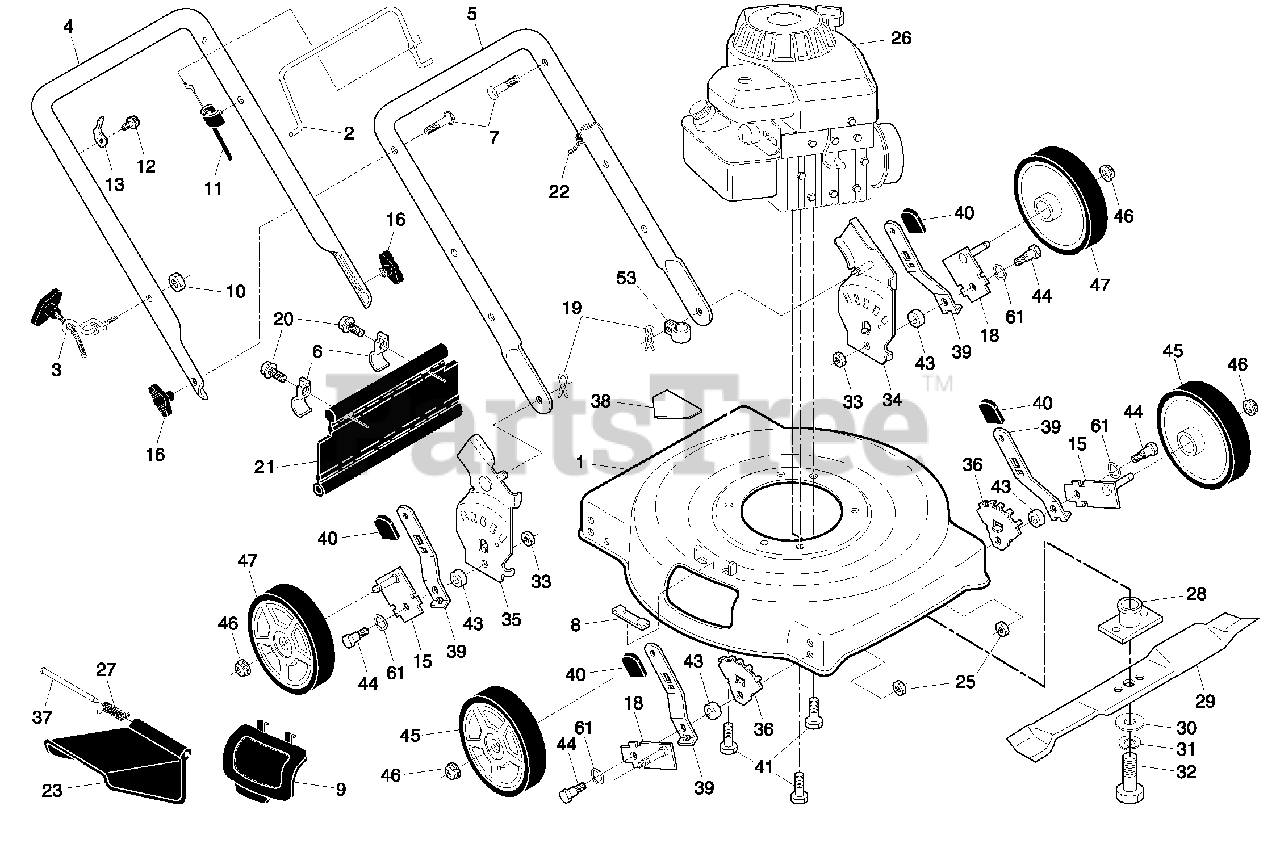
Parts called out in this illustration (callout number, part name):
1	Lawn Mower Housing Assembly
2	Control Bar
3	Rope Guide
4	Upper Handle
5	Lower Handle
6	Hinge Bracket
7	Handle Bolt 5/16-18
8	Clip, Closeout
9	Mulcher Plate
10	Locknut, Hex 1/4-20
11	Engine Zone Control Cable
12	Screw, Hex Head, Threaded, Rolled #10-24 x1/2
13	Up-Stop Bracket
15	Axle Arm Assembly (Rear, RH / Front, LH)
16	Handle Knob
18	Axle Arm Assembly (Rear, LH / Front, RH)
19	Hairpin Cotter
20	Screw
21	Rear Skirt
22	Wire Tie
23	Discharge Guard
25	Nut, Hex
27	Torsion Spring
28	Blade Adapter
29	22" Blade
30	Hardened Washer
31	Helical Lockwasher 3/8
32	Hex Head Screw 3/8-24 x 1/4 Grade 8
33	Nut, Hex, Centerlock 5/16-18
34	Support, Wheel Bracket, LH
35	Support, Wheel Bracket, RH
36	Adjuster, Wheel Bracket
37	Hinge Rod
38	Danger Decal
39	Selector Spring
40	Selector Knob
41	Screw, Hex Head, Threaded, Rolled 3/8-16 x 1
43	Spacer
44	Shoulder Bolt
45	Wheel & Tire Assembly, Front
46	Locknut, Hex 3/8-16
47	Wheel & Tire Assembly, Rear
53	Clip, Cable
61	Washer, Curved, Cylindrical
61	Operator's Manual, English
61	Operator's manual, Spanish
61	Repair Parts Manual
